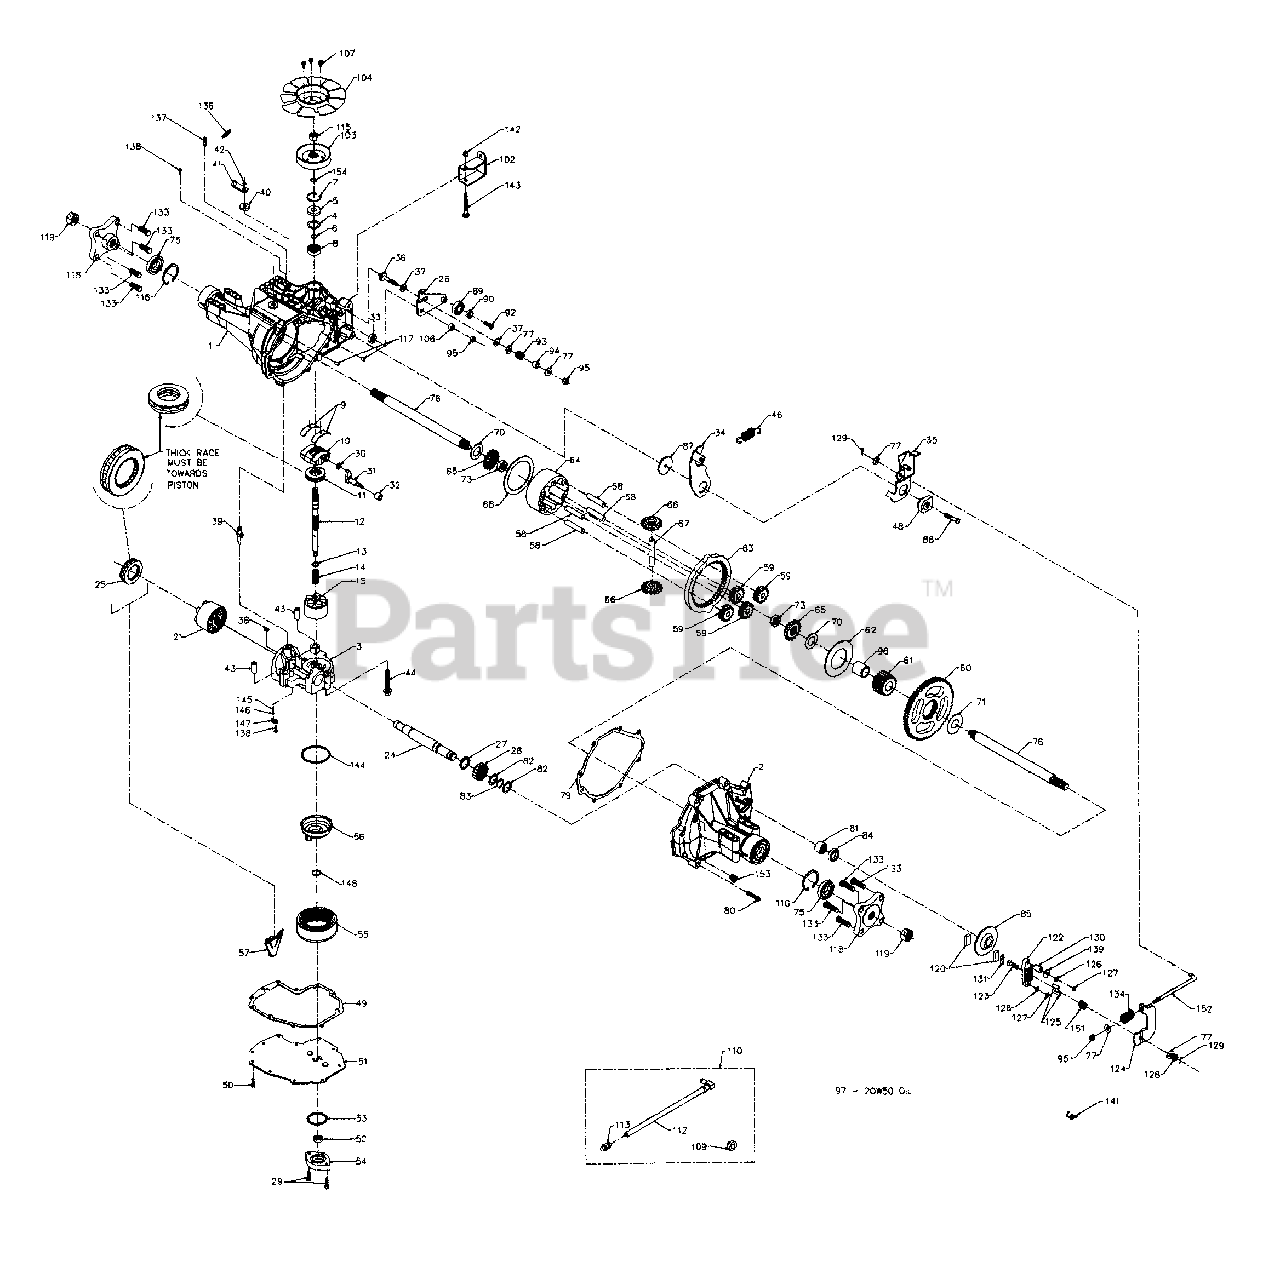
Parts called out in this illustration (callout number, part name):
1	Main Housing Ass'y.
2	R.H. Housing Ass'y.
3	Center Section Ass'y.
6	Wire Retaining Ring
7	Retaining Ring
8	Ball Bearing
9	Cradle Bearing
10	Variable Swashplate
11	Thrust Bearing
12	Input Shaft
13	Block Thrust Washer
14	Block Washer
15	Cylinder Block Ass'y.
21	Cylinder Block Ass'y.
24	Output Shaft
25	Thrust Bearing
26	Control Arm
27	Spacer
28	16T Pinion Gear
29	Capscrew M6 x 1-20
30	Slot Guide
31	Trunnion Arm
32	Trunnion Bushing
34	Return Arm
35	Actuating Arm
36	Stud 5/16-24 Thd.
37	Friction Puck
38	Bypass Plate
39	Bypass Actuator
41	Bypass Arm
42	Retaining Ring
44	Screw
46	Neutral Spring
48	Adjusting Spring
49	Lower Gasket
50	Self-Tapping Screw
51	Lower Cover
52	Gerotor Ass'y.
54	Gerotor Cover
55	Filter
56	Charge Manifold
57	Retainer, Motor Bearing
58	Pin, Carrier
59	15T Planet Gear
60	67T Spur Gear
61	21T Sun Gear
62	Planet Thrust Plate
63	51T Ring Gear
64	Planetary Carrier
65	Miter Gear
66	Miter Gear
67	Shaft, Differential
68	Differential, Thrust Plate
70	Washer
71	Washer
73	Hex Jam Nut 5/8-18 Thd.
75	Seal
76	Shaft, Axle
77	Washer
79	Gasket, Main Housing
80	Torx Hd. Scr. 5/15-18 Thd.
81	Needle Bearing
82	Washer
83	Retaining Ring
85	Brake Disk
87	Washer
88	Screw 5/16-24 x 1.75" Lg.
89	Bearing
90	Spacer, Locating
92	Countersunk Screw
93	Spring
94	Spacer
95	Hex L-Nut 5/16-24 Thd.
96	Sleeve Bearing
97	Oil (.91 Gal.)
102	Torque Bracket
103	Pulley
106	Spacer, Trunnion
107	Screw
109	Vent Bushing
110	Fitting Kit
112	Hose Fitting Ass'y.
113	Cap-Vent Ass'y.
115	Jam Nut
116	Retaining Ring
117	Std. Handle Pin
119	Hex Nut 3/4-16 Thd.
120	Puck, Brake
122	Brake, Yoke
123	Bolt, Square Head
124	Arm, Brake
125	Pin, Brake
126	L-Wash. 1/4" I.D.
127	Hex Nut 1/4-20 Thd.
128	Castle Nut
129	Cotter Pin
130	Spacer
131	Puck Plate
133	Wheel Stud
134	Brake Spring
136	Extension Spring
137	Spring Pin
138	Screw, Self-Tapping 10-32 x .5"
139	Washer .265" I.D. x .875" O.D.
141	Spring, Brake
142	Hex L-Nut 5/16-18 Thd.
143	Bolt 5/16-18 x 2.5" Lg.
144	O-Ring
145	Relief Spring
147	Plate, Relief
148	O-Ring
151	Brake Comp. Spring
152	Brake Pull Rod
154	Wire Retaining Ring
